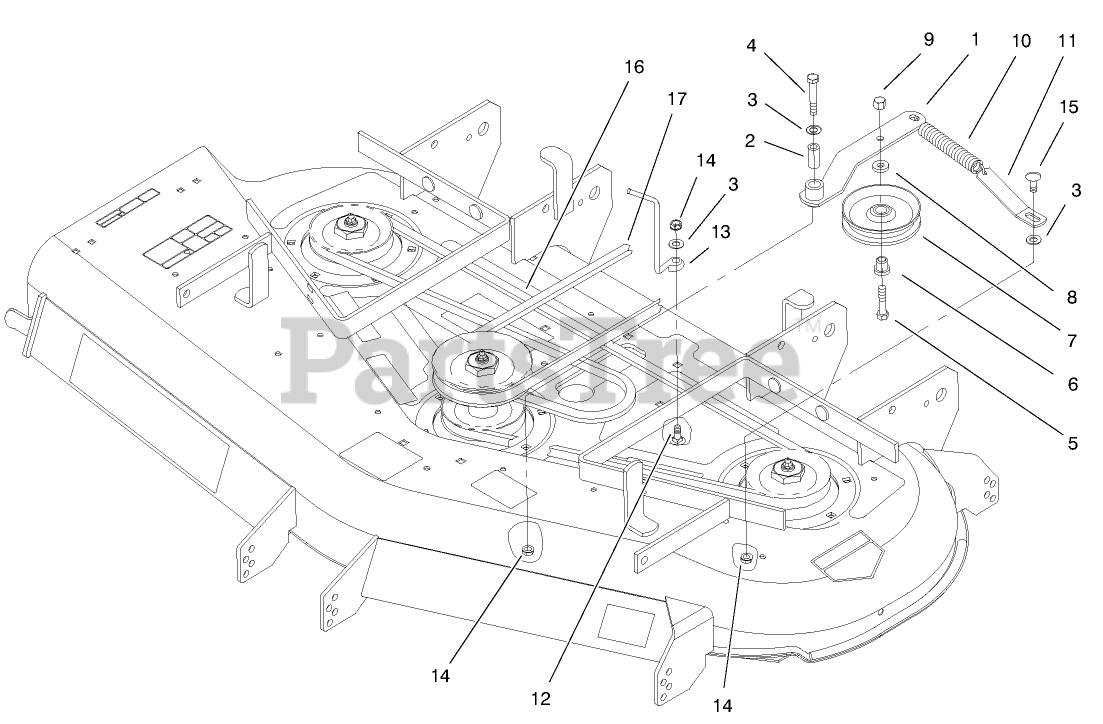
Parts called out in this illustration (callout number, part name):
1	IDLER ARM ASM
2	SLEEVE
3	WASHER-FLAT
4	SCREW-HH
5	SCREW-HH
6	BUSHING-PULLEY
7	PULLEY-IDLER
8	WASHER-FLAT
9	NUT-HEX
10	SPRING-EXTENSION
11	PLATE-SPRING
12	SCREW-CARR
13	GUIDE-BELT
14	NUT-HF
15	SCREW-CARR
16	V-BELT
17	BELT (52)
